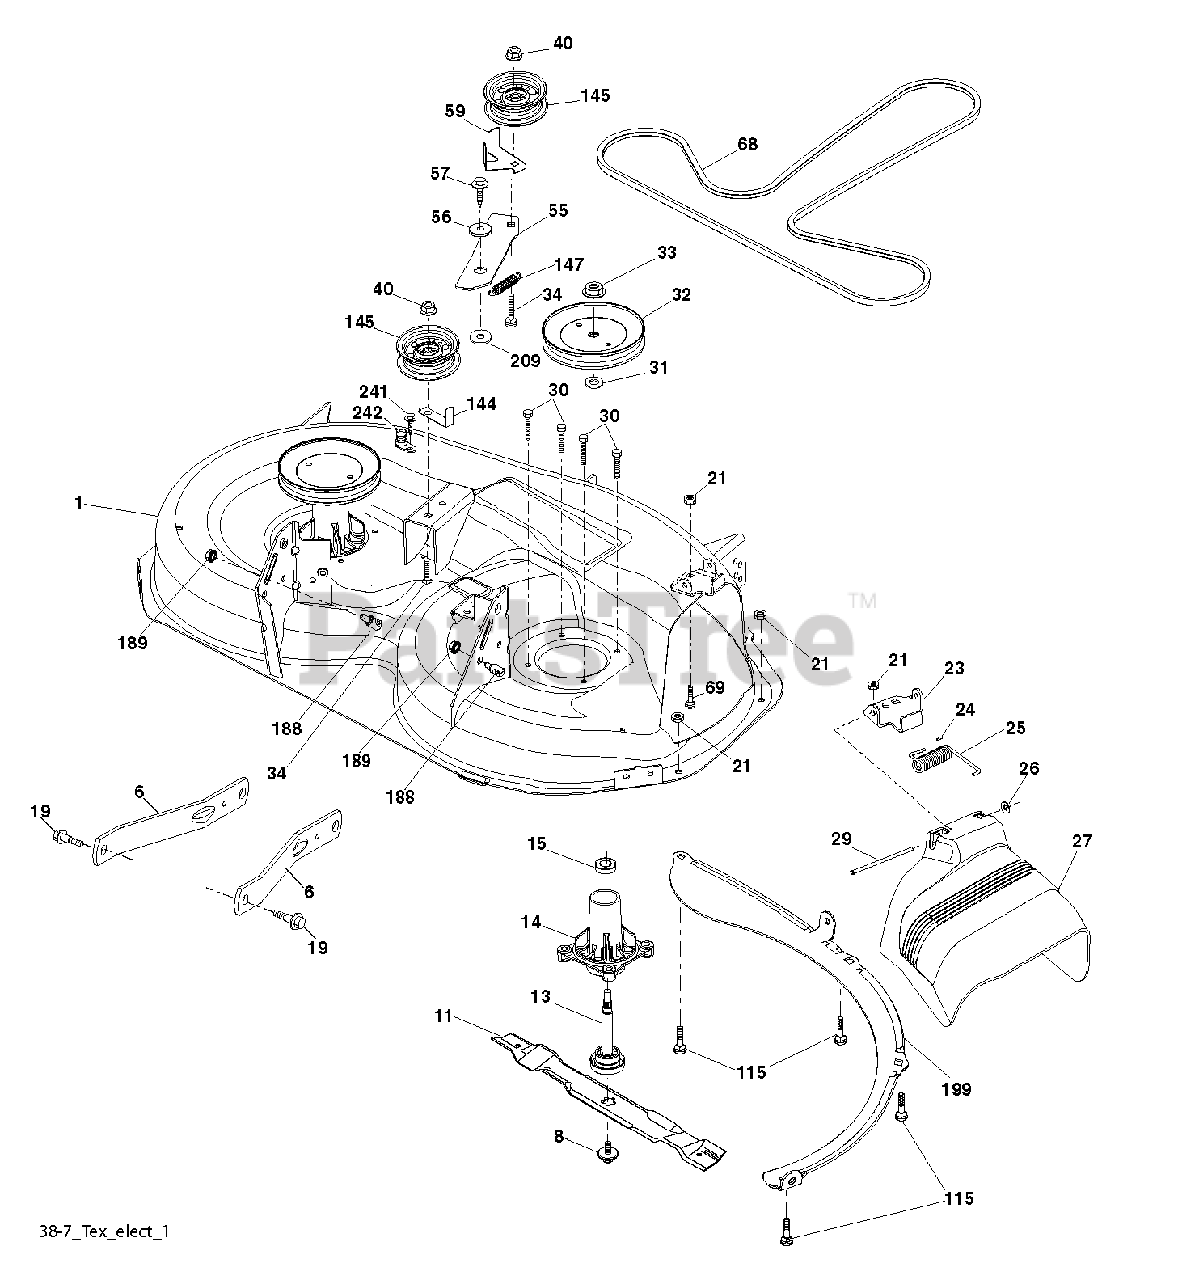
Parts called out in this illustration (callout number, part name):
1	DECK.WELD.38.NGW.TX.W/HOL.GREY
6	ARM.SUSPENSION.MOWER.R
8	BOLT.WASHER.ASM.7/16-2
11	BLADE.HI.LIFT.38"
13	SHAFT.ASM.MDRL.N/GREASE.38
14	HOUSING.MANDREL.4PT.
19	BOLT.SHOULDER
21	LOCKNUT
23	BRKT.DEFLECTOR.38"2005+
24	CAP-SLEEVE LT
25	SPRING.TORSION.DEFLECT
26	NUT PUSH M
27	SHIELD.DEFLECTOR.MWR.38-7/97CM
29	ROD.HINGE
30	SCREW, WASHER HEAD
31	WASHER.SPACER.MANDREL
32	PULLEY MANDREL
33	NUT.FLANGE.LOCK.TOP
34	BOLT.3/8-16X1.50
40	NUT LOCK FLG 3/8-16 UNC
56	SPACER.RETAINER
57	SCREW 3/8-16X1
59	GUARD, BELT
69	BOLT
115	BOLT
144	KEEPER BELT
145	PULLEY.IDLER.48"PRIMARY
147	SPRING RETURN
188	STUD.FASTNER.W/ANTI-ROTATE
189	NUT LOCK HEX FLANGE 5/16-18
199	BAFFLE.VORTEX.FRONT.38"
209	WASHER 12/32X2X10GA
241	SCREW.TT.#10-32X.5.3/8.FLANGE
242	PORT.WASHOUT
